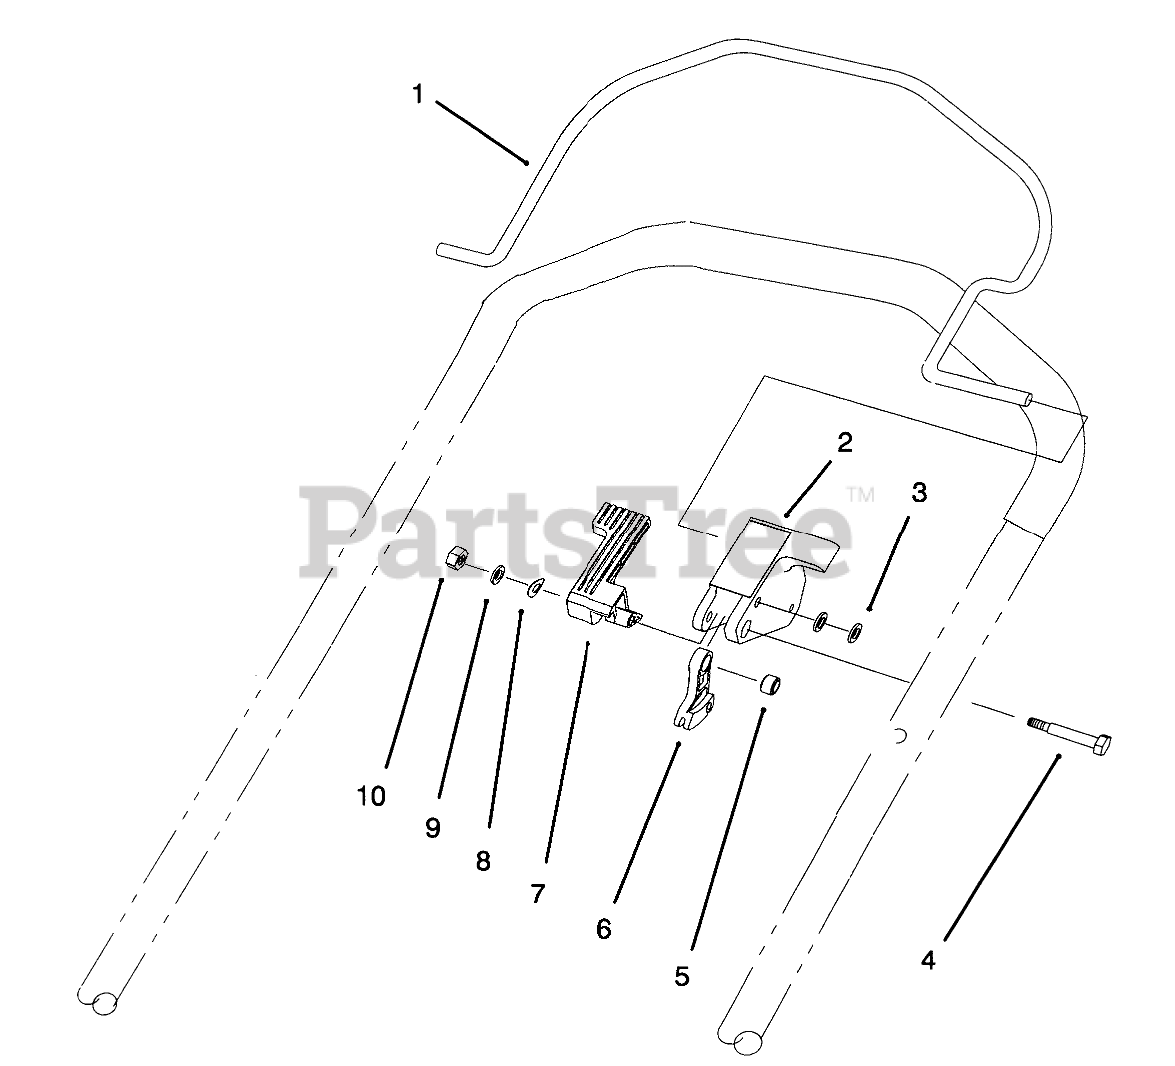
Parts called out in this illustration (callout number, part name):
1	BAIL - CONTROL
2	STOP - PIVOT, PLASTIC
3	WASHER-FLAT
4	SHOULDER BOLT
5	SPACER-LEVER, TRACTION
6	LEVER-TRACTION
7	LEVER - SHIFT
8	WASHER - SPRING
9	WASHER-PLAIN
10	NUT-LOCK, NI
